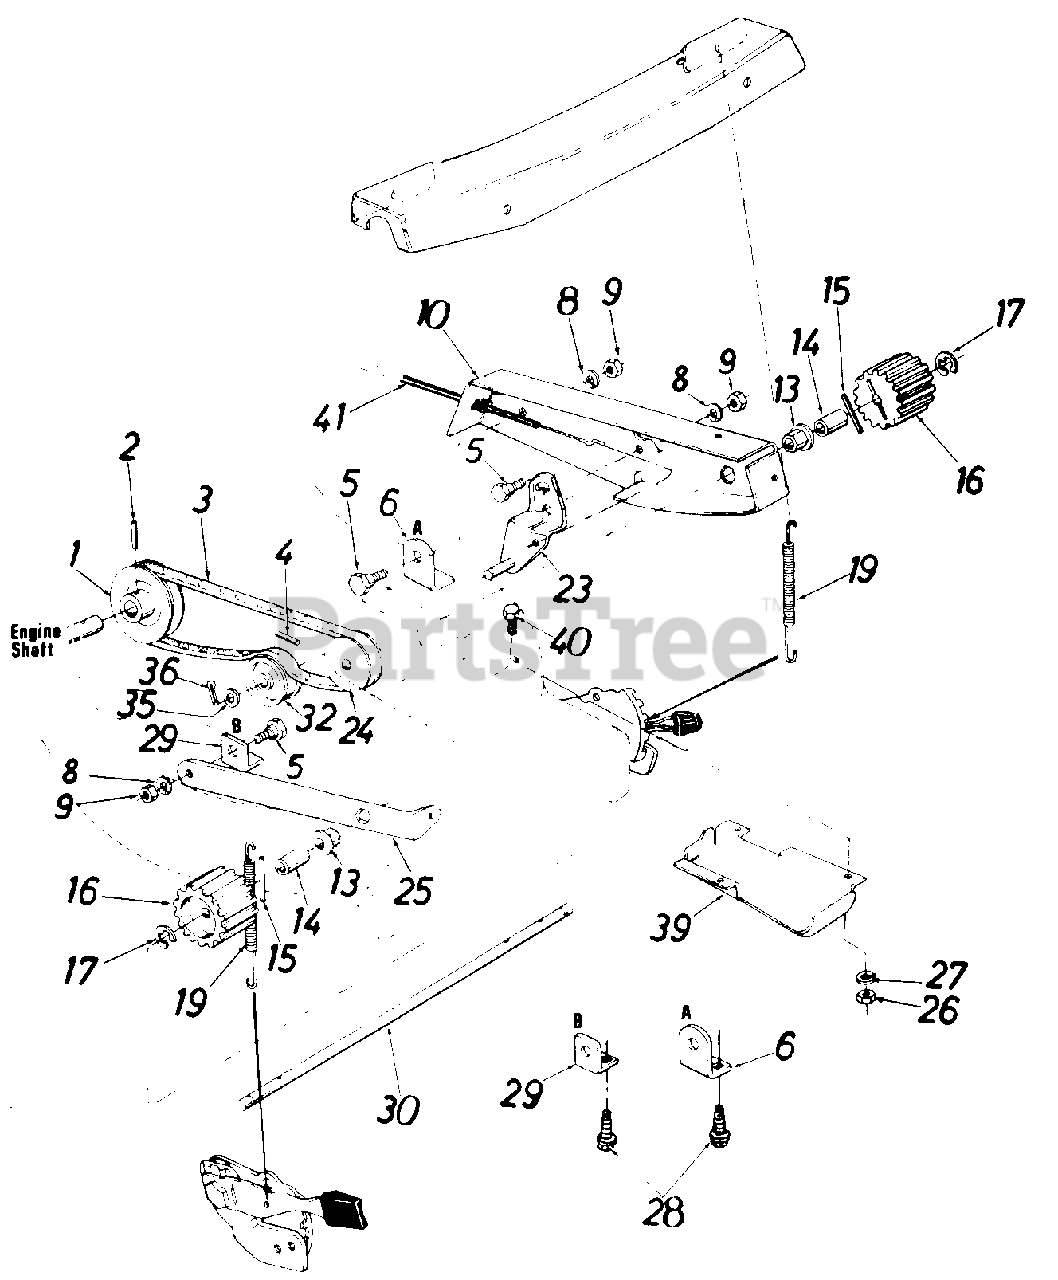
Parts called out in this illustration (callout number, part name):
1	1/2 "V"-Engine Pulley
2	Spring Pin Spiral 3/16" Dia. x 1.25" Lg.
3	"V"-Belt 1/2" x 28.0" Lg.
4	Spring Pin Spiral 3/16" Dia. x 1.00" Lg.
5	Shld. Bolt .500 Dia. x .170
6	Belt Cover Pivot Brkt.
8	L-Wash. 3/8" I.D.
9	Hex Jam Nut 3/8-16 Thd.
10	Belt Cover Ass'y.
13	Hex Flange Brg. .503 I.D.
14	Spacer .52 I.D. x .69 O.D.
15	Spring Pin Spiral 3/16 Dia. x 1.25" Lg.
16	13 Teeth Drive Pinion
17	"E"-Ring for .500 Dia. Shaft
19	Extension Spring-3.25"
23	Idler Brkt. Ass'y.
24	1/2"V"-Pulley
25	Cover Support Brkt.
26	Hex Nut 1/4-20 Thd.*
27	L-Wash. 1/4" I.D.*
28	Hex Wash. Hd. Self-Tap Scr. 1/4-20 x .50" Lg.
29	Cover Support Pivot Brkt.
30	Pinion Shaft
32	Plastic Flat Idler
35	Fl-Wash. .53 I.D. x .93 O.D.
36	Cotter Pin 1/8" Dia. x 1.0"*
39	Belt Cover Baffle
40	Truss Mach. Scr. 1/4-20 x .50" Lg.*
41	S.P. Cable-53"-Yellow
